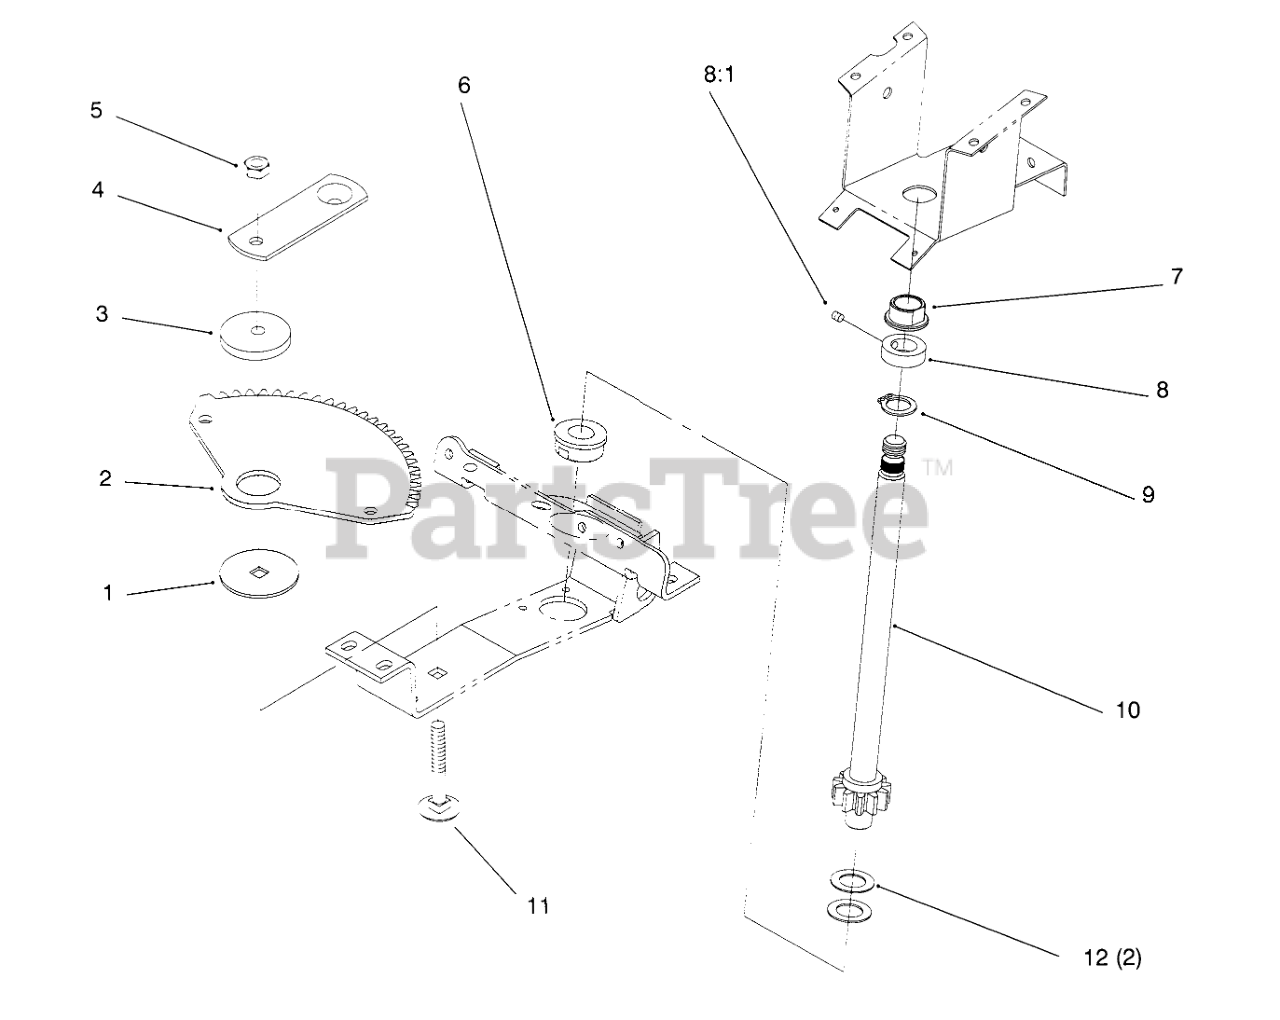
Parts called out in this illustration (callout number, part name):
1	WASHER-BEARING
2	GEAR-SECTOR
3	BUSHING
6	BEARING-WHEEL
7	BEARING-FLANGED
8	COLLAR
8:1	SCREW-HSH
9	RING-RETAINING
10	SHAFT-STEERING, LOWER
11	SCREW-CARR
12	WASHER
